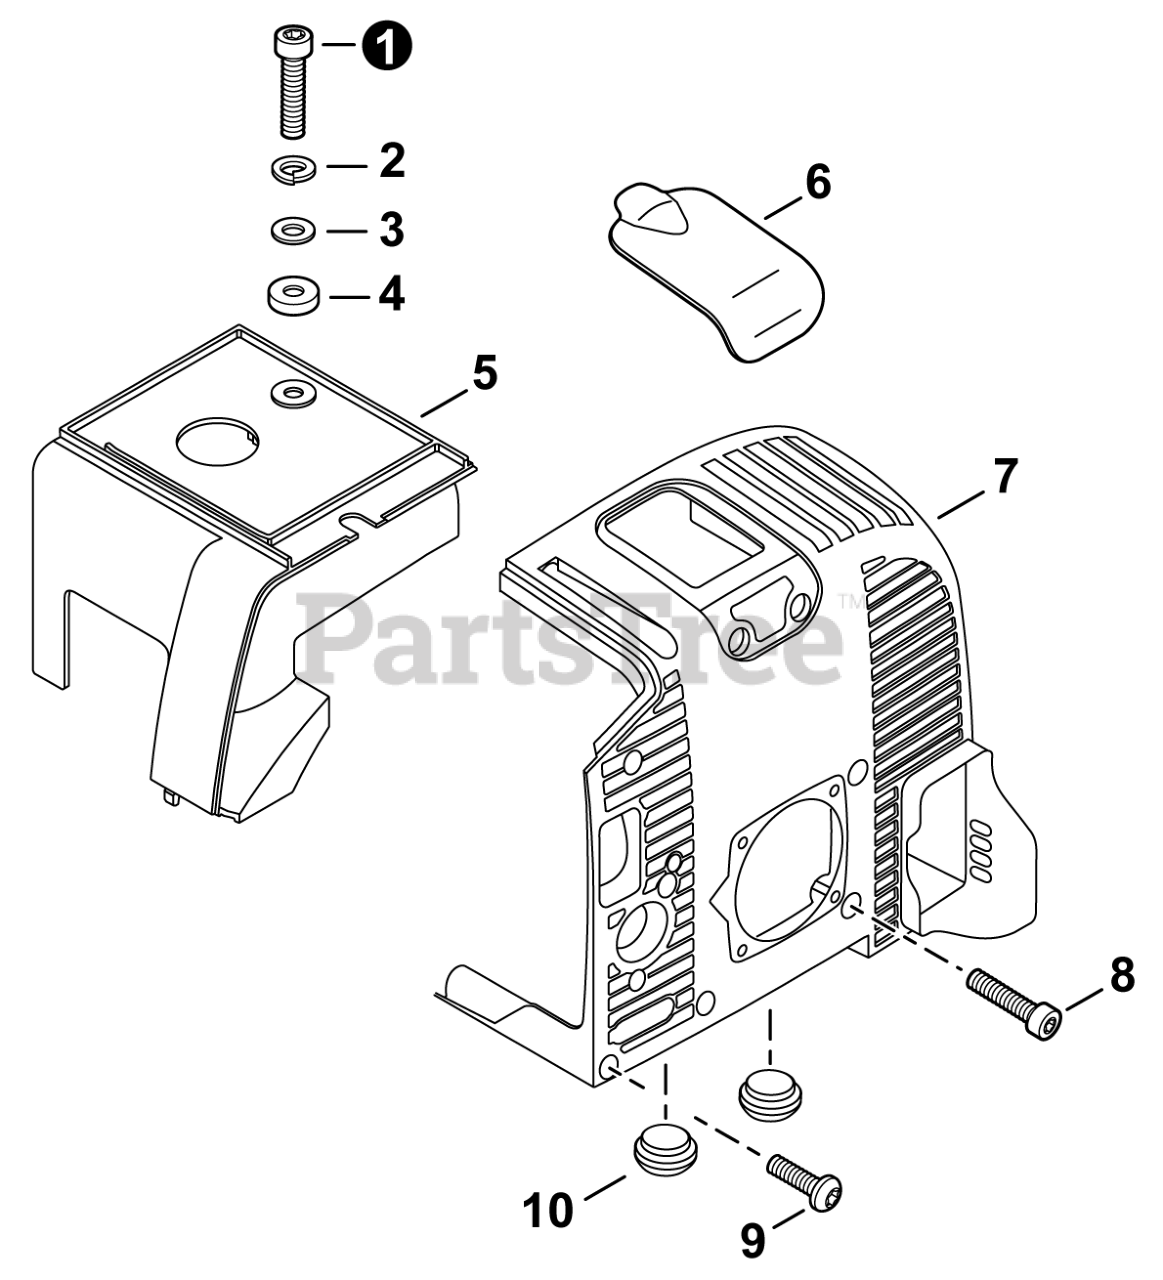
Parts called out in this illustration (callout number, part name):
1	BOLT 5x20
2	WASHER, SPRING 5
3	WASHER, FLAT 5.5x10x0.8
4	WASHER 5.2x14xT3
5	COVER, CYLINDER
6	COVER, SPARK PLUG
7	COVER, ENGINE
8	BOLT, TORX 5x16
9	BOLT, TORX 5x20
10	CUSHION
